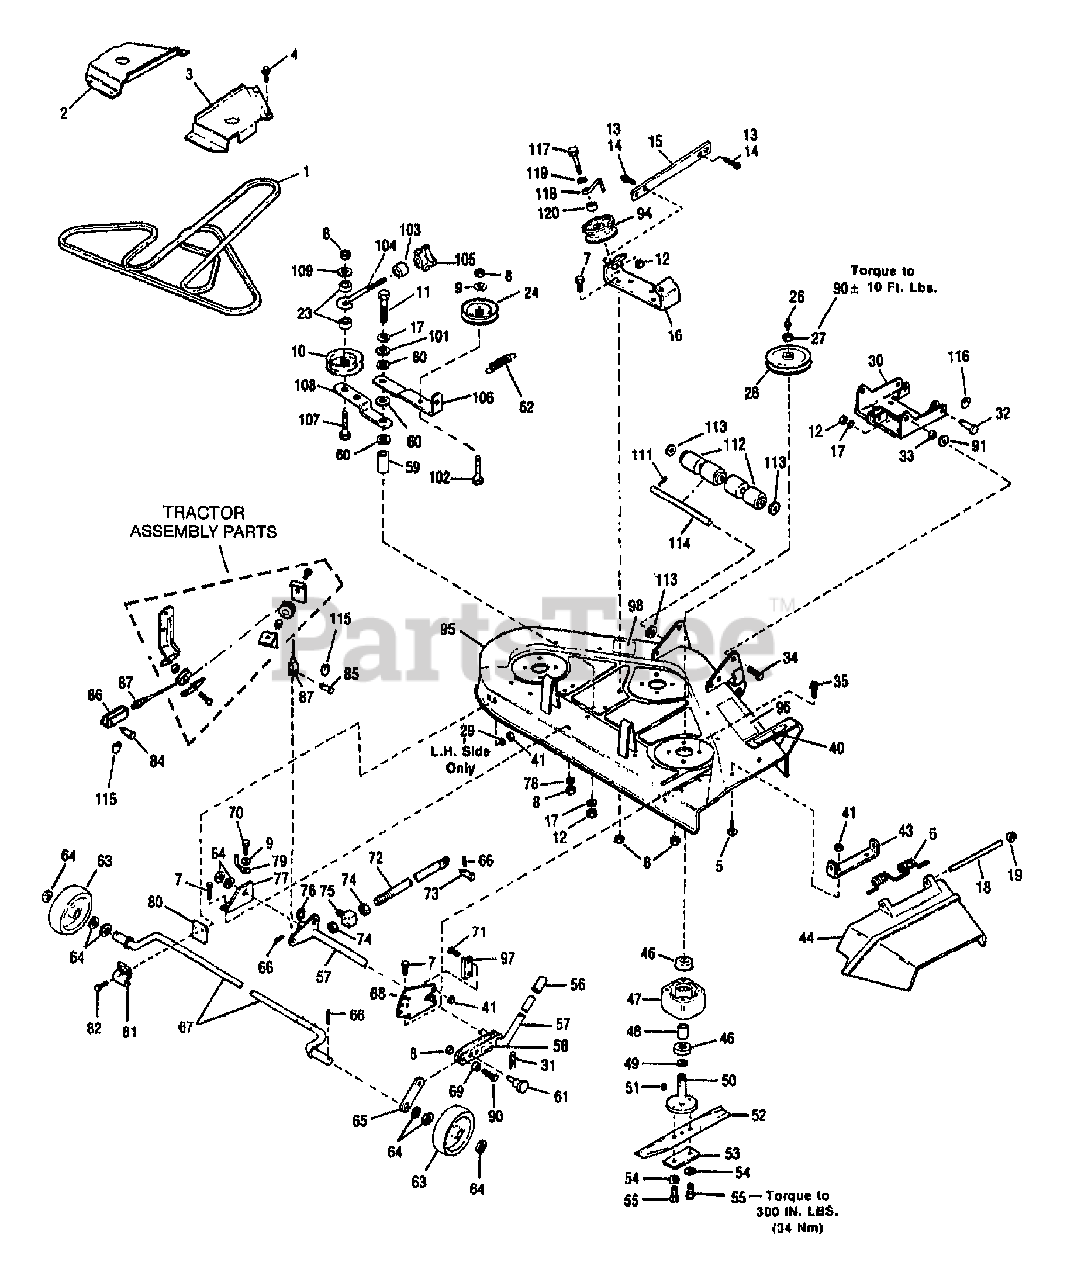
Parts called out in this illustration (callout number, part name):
1	BELT
2	COVER-BELT LH
3	COVER-BELT RH
4	SCR 1/4-20X.5 FL SELF TAP
5	BOLT-CARR 5/16-18X.63 ZP
6	SPRING-TORSION
7	SCR-HH 3/8-16X1.0 G5 ZP
8	NUT-LOCK 3/8-16
9	WASHER-FLAT 3/8 SAE
11	SCR-HH 1/2-13X2.0 G5 ZP
12	NUT-TOP LOCK 1/2-13 ZP
13	SCR-HFLK 3/8-16X1.00 ZP
14	NUT-HFLK 3/8-16 ZP
16	BRKT-IDLER SUPPORT
17	WASHER-1/2 FLAT
19	NUT-PUSH 3/8 ZP
26	FITTING-GREASE 1/4-28X2.00
27	NUT-H/LK
29	WASHER-LOCK
30	ASSM-MOWER SUPT
31	PIN-HITCH .125X2.56 ZP
32	PIN-CLEVIS .62X2.50 ZP
33	SPACER-TUBULAR
34	SCR-HH 1/2-13X1.25 G5 ZP
35	SCR-HFLK 5/16-18X.75
40	DECAL-CUTTING LINE
41	NUT-TOP/LK 5/16-18 ZP
44	DEFLECTOR-DISCHARGE
46	BEARING-BALL
47	HOUSING-SPINDLE
49	WASHER-SPECIAL
50	SHAFT
51	KEY-WOODRUFF .188X.75
52	BLADE-42" GRS DECK
53	PLATE
54	WASHER-LK .375 @ DEPL
55	SCR-HH 3/8-24X1.0 G5 ZP
56	GRIP-HANDLE BLACK
57	ASSM-WHEEL HGT ADJ
58	DECAL-CUTTING HEIGHT
60	WASHER-THRUST
62	SPRING-IDLER
63	GAUGE-WHEEL
64	WASHER-1.38 X.765X .06 ZP
65	LINK-WHEEL SUPT
66	PIN-COTTER .120X1.25 ZP
67	SUPT-WHEEL SHAFT
69	SPACER-.75X.40X.51 P/M
70	SCR-HH 3/8-16X1.25
71	SCR-HH 5/16-18X.63 G5
72	ROD-ADJUSTER
73	PIN-CLEVIS .5X1.75 ZP
74	NUT-HEX
75	BLOCK-PIVOT
76	RING-RETAINING EXT .694 ID
77	BRKT-SUPPORT
78	WASHER-FLAT 1.25X.406X.179
79	GUIDE-BELT
80	PLATE-DOUBLER
81	SUPPORT-SHAFT
82	SCR-HH 5/16-18X1.0 G5 ZP
84	PIN-CLEVIS .5X1.437 ZP
85	PIN-CLEVIS .375 X .937 ZP
86	YOKE
87	ASSM-CABLE(MOWER DECK)
90	SCR-HH 3/8-16X1.5 G5 ZP
91	WASHER
95	ASSM-BASE
96	DECAL-OPEI CAUTION
97	RETAINER-SHAFT
98	DECAL-BELT ARRANGEMENT
101	WASHER-WAVE .99X.76X.022
102	SCR-HH 5/16-18X.875 G5 ZP
103	WASHER-1.0X.39X.4 ZP
107	SCR-HH 3/8-16X2.25 G5 ZP
109	WASHER-.875X.390X.134
111	PIN-COTTER .120X1.00 ZP
112	ROLLER
113	WASHER-1.305X.649X.098 ZP
114	ROLLER
115	RING-CIRCLE COTTER
116	RING-COTTER
117	SCR-HH 1/2-13X3.25 G5 ZP
118	GUIDE-BELT
119	WASHER-1.06X.531X.1 ZP
120	SPACER
